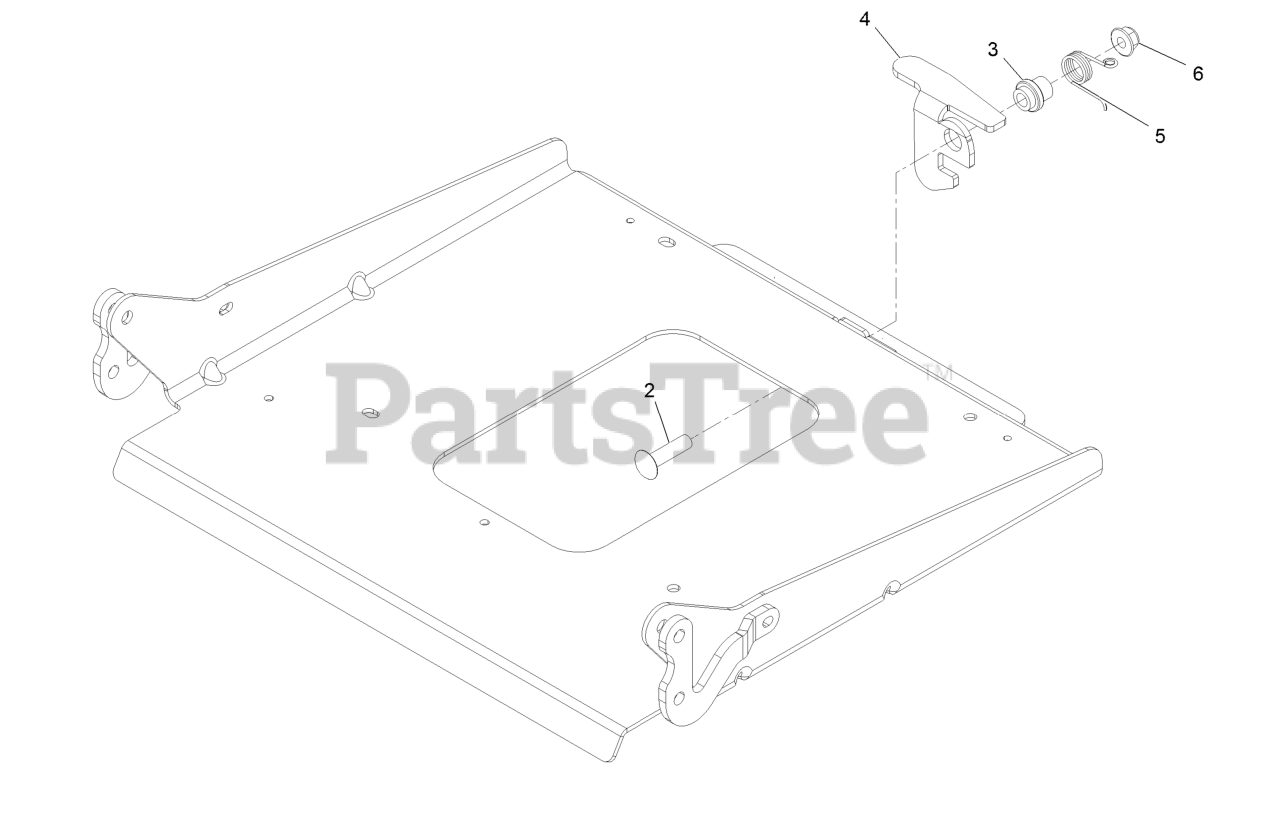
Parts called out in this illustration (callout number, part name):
2	Screw-CARR
3	Bushing-Latch, Seat
4	Latch-Catch, Single
5	Spring-Torsion, Latch
6	Nut-HF, NI
